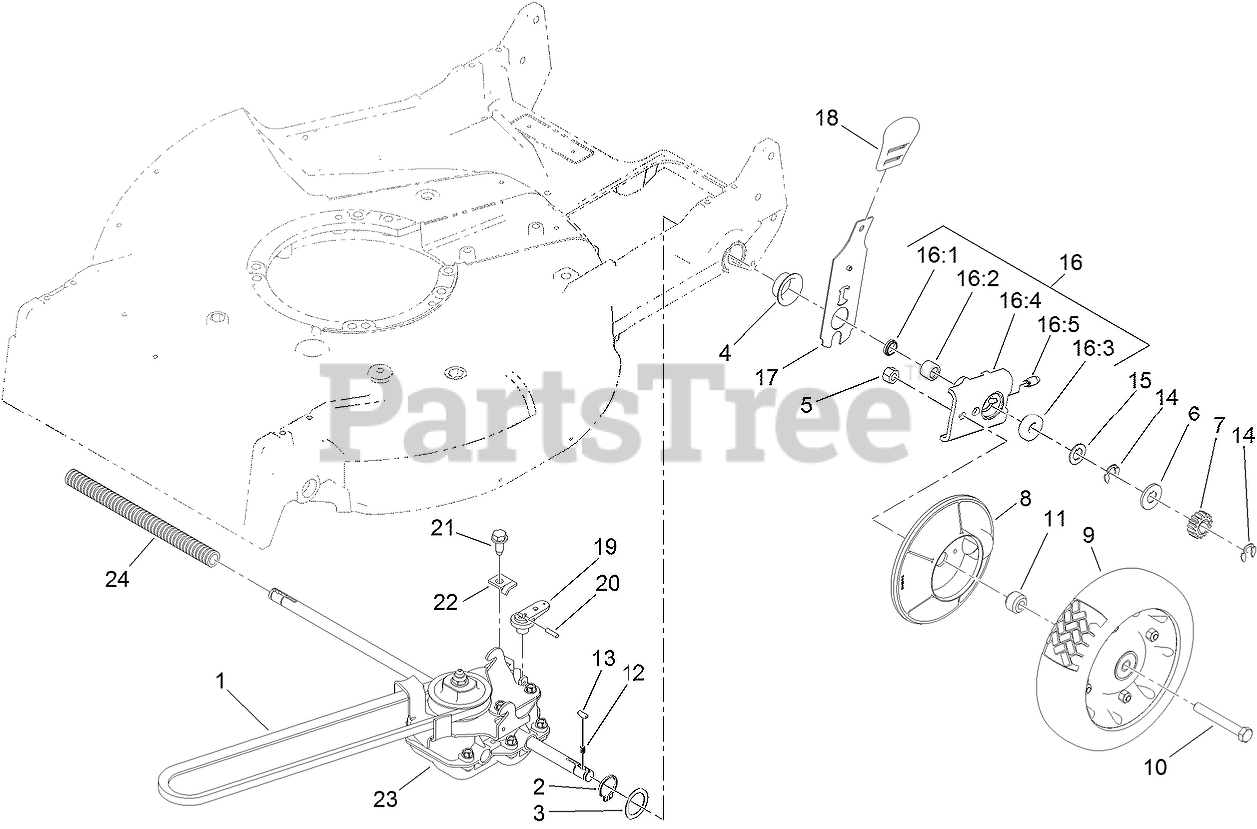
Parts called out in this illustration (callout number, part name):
1	V-BELT
2	RING-RETAINING
3	WASHER
4	CAP-END
5	NUT-LOCK, CONE
6	WASHER-THRUST, OUTER
7	GEAR-PINION
8	COVER-WHEEL
9	WHEEL AND TIRE ASM
10	SCREW-HH
11	SPACER-COVER, WHEEL
12	SPRING-COMPRESSION
14	RING-RETAINING
15	WASHER-THRUST, OUTER
16	PIVOT ARM ASM
16:1	SEAL-OIL
16:2	BEARING-CAGED NEEDLE ROLLER
16:3	BEARING-WHEEL
16:4	Arm-Pivot, Rear
17	REAR SPRING ARM ASM
18	KNOB-HOC
19	LEVER-SHIFT
20	PIN-COIL
21	SCREW-HWHTF
22	CLAMP-CABLE
23	GEAR CASE ASM
24	COVER-SHAFT, DRIVE
